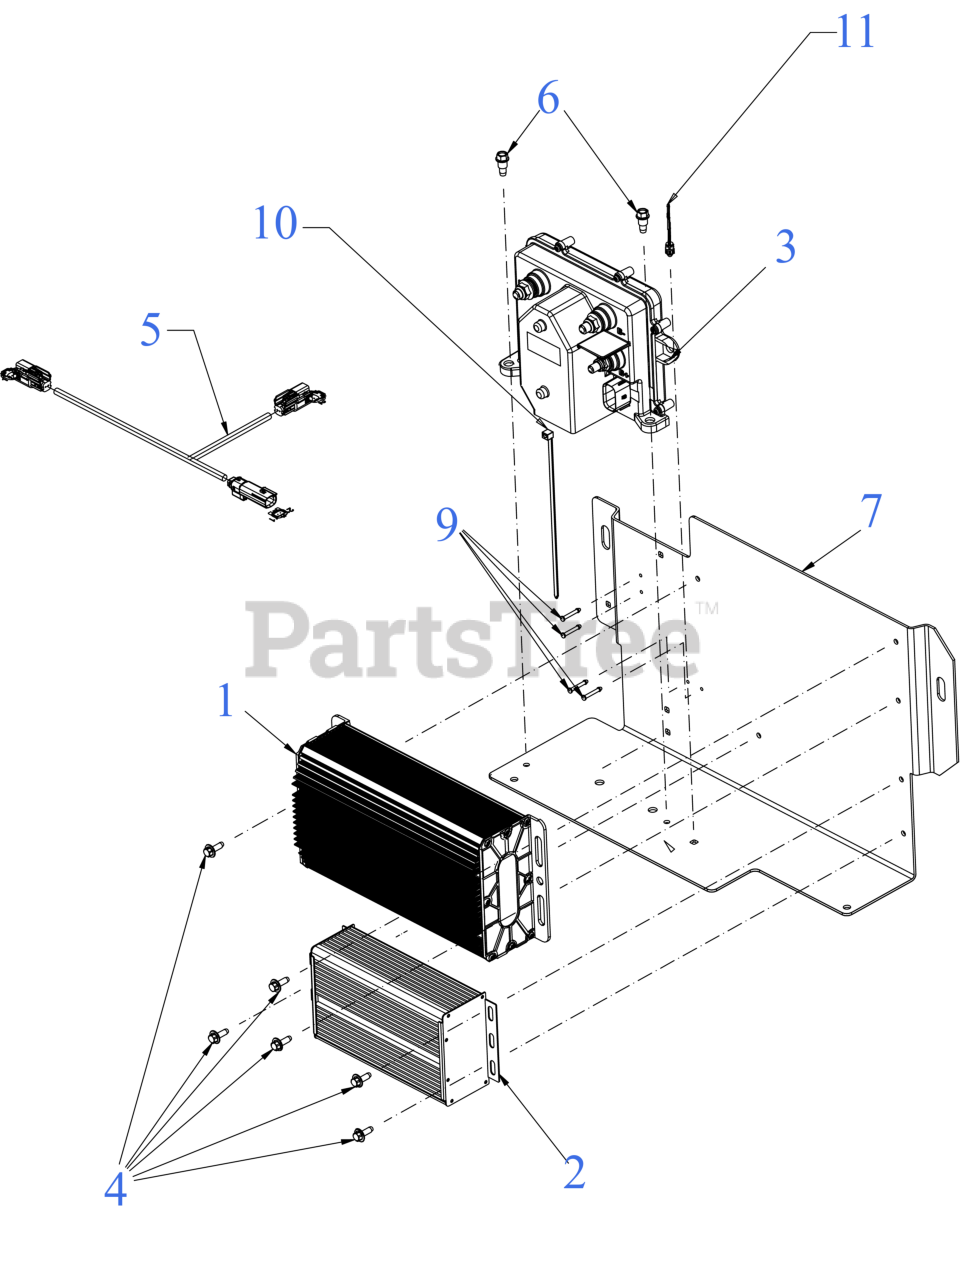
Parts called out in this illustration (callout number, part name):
1	MOTOR CONTROLLER (DECK)
2	MOTOR CONTROLLER (DRIVE)
3	PDM HOUSING (2FUSE)
4	SCREW M6-1 x .625
5	CANBUS HARNESS
6	SHOULDER SCREW
7	MOUNT BRACKET
9	PANEL RATCHET CLIP .125 x .750
10	7" CABLE TIE
11	TWIST LOCK CLIP
